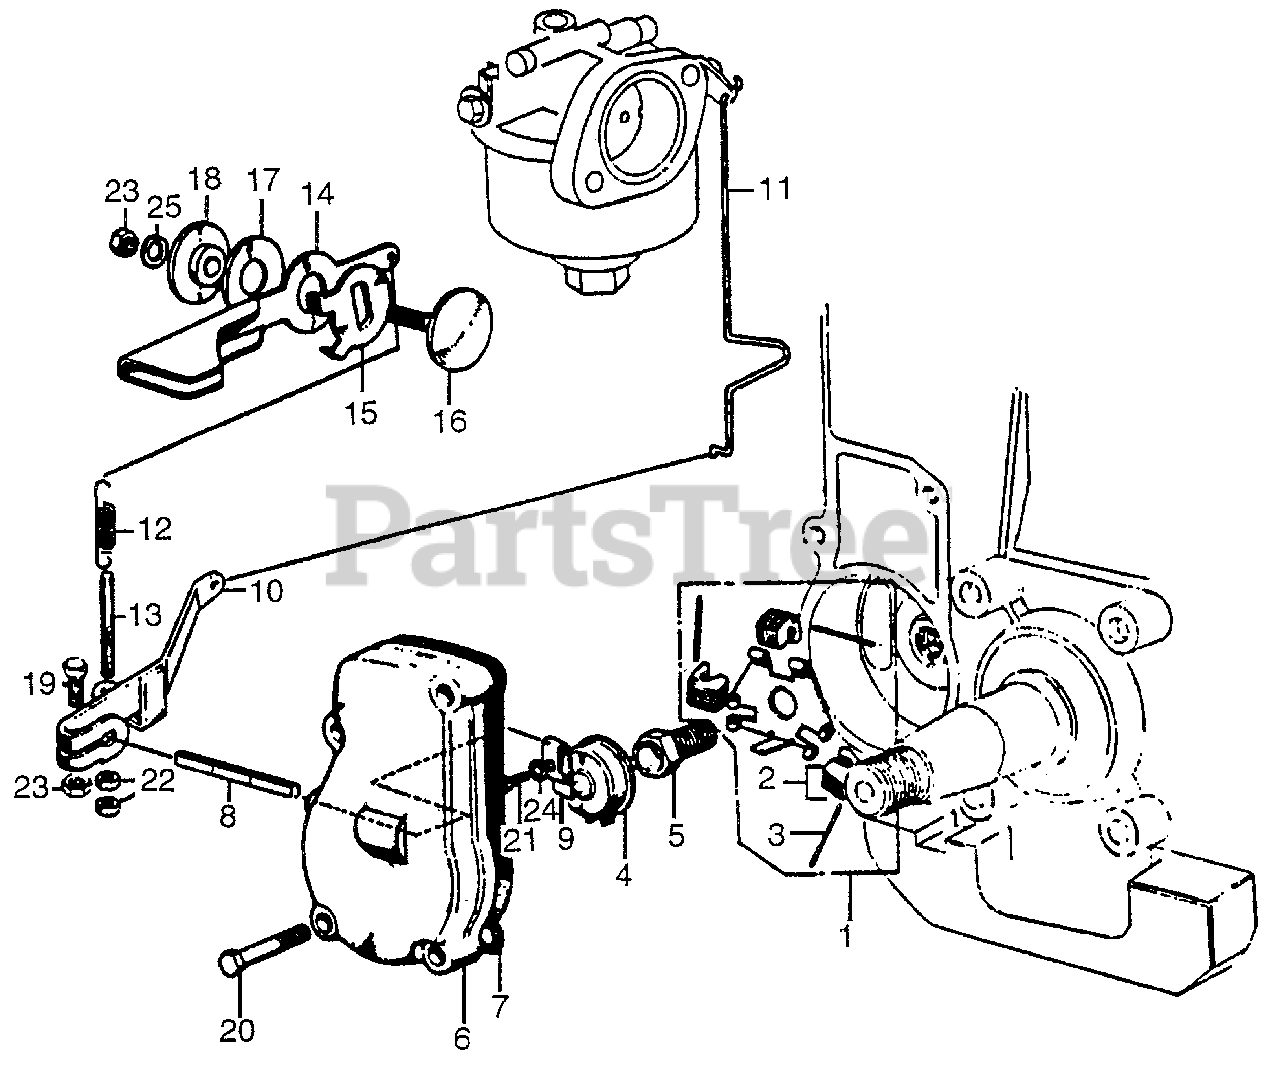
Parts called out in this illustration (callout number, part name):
1	HOLDER, GOVERNOR WEIGHT
2	WEIGHT, GOVERNOR
3	PIN, GOVERNOR WEIGHT
4	SLIDER, GOVERNOR (NOT AVAILABLE)
5	BOLT, GOVERNOR SET
6	COVER, GOVERNOR
7	GASKET, GOVERNOR COVER (NOT AVAILABLE)
8	SHAFT, ARM
9	ARM, LEVER
10	ARM, GOVERNOR
11	ROD, GOVERNOR
12	SPRING, GOVERNOR (NOT AVAILABLE)
13	BOLT, SPRING ADJUSTING
15	STOPPER, LEVER (NOT AVAILABLE)
16	BOLT, LEVER
17	SPRING, LEVER
18	SPACER, LEVER
19	BOLT, HEX. (6X16)
20	BOLT, HEX. (6X25)
21	SCREW, PAN (4X8)
22	NUT, HEX. (4MM)
23	NUT, HEX. (6MM)
24	WASHER, SPRING (4MM)
25	WASHER, SPRING (6MM)
